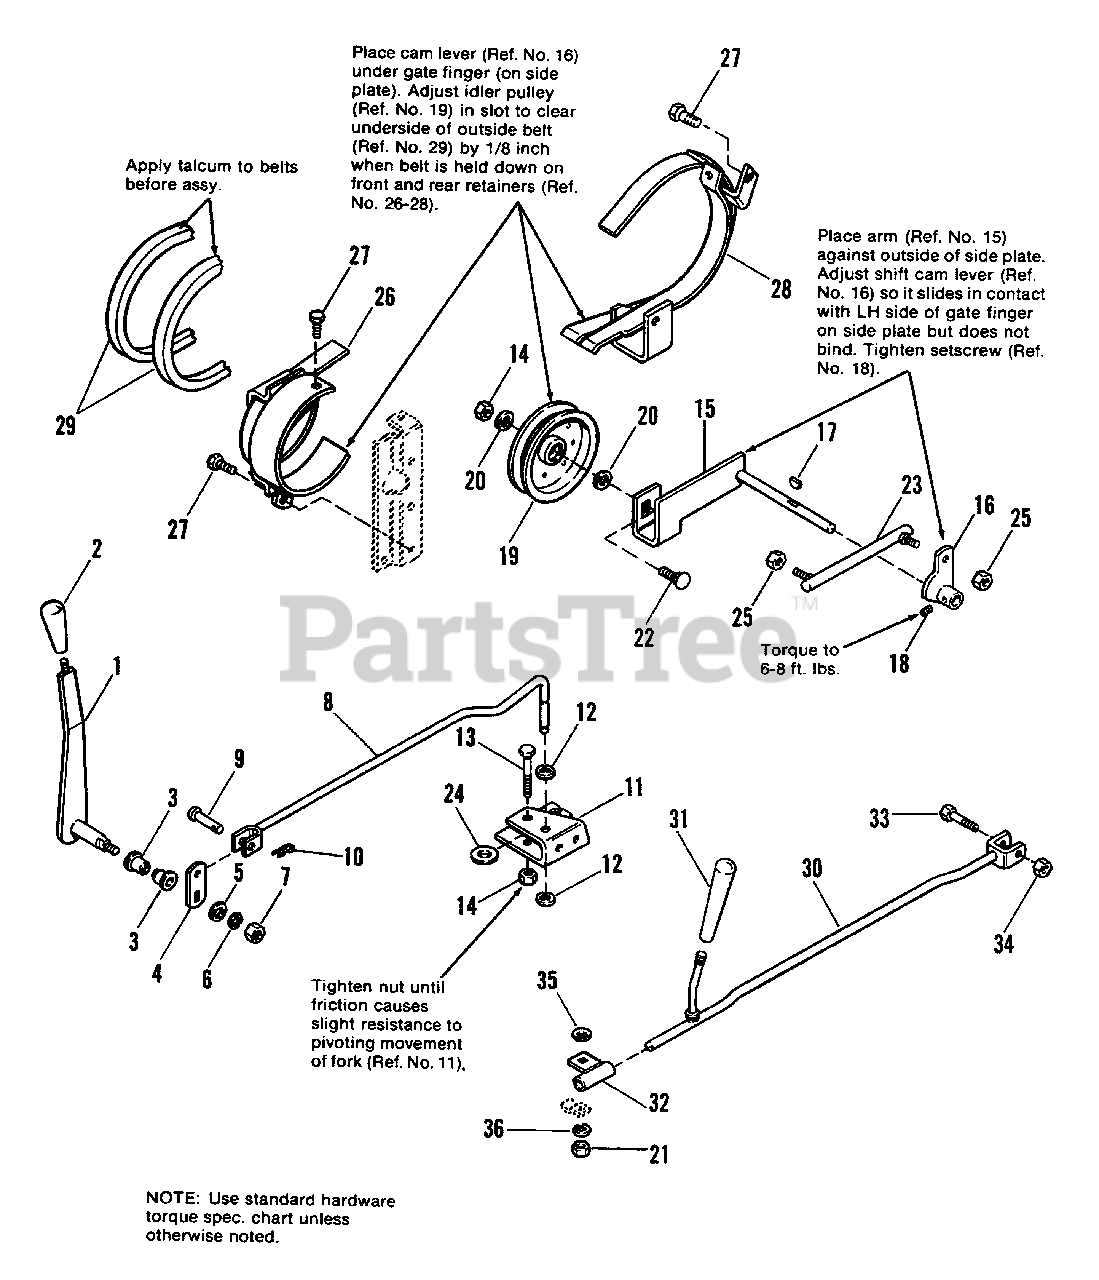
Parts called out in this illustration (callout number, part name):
1	CONTROL LEVER ASSY.
2	KNOB
3	BUSHING, Flanged
5	WASHER, 3/8
6	LOCKWASHER, 3/8
7	NUT, Hex, Full, 3/8-16
8	CONTROL ROD ASSY.
10	PIN, Cotter, 3/32 x 3/4
11	FORK, Shift
12	"E" RING, External
13	CAPSCREW, Hex Hd., 3/8-16 x 2
14	LOCKNUT, Hex, 3/8-16
15	IDLER ARM ASSY.
16	CAM SHIFT LEVER ASSY.
17	KEY, Woodruff, #5, 1/8 x 5/8
18	SETSCREW, Sq. Hd., 1/4-20 x 1/4
19	PULLEY, Idler
20	WASHER, 5/16
21	NUT, Hex, Full, 1/4-20
22	BOLT, Carriage, 3/8-16 x 1-1/4
23	JOINT, Ball, Dbl. End
25	LOCKNUT, Hex, Full, 5/16-24
26	BELT RETAINER ASSY.
27	SCREW, Taptite, 5/16-18 x 1/2
28	REAR RETAINER ASSY.
29	BELT,"V", Drive
30	SHIFT ROD ASSY.
31	HANDLE, Shift Rod
32	SHIFT ROD GUIDE ASSY.
33	CAPSCREW, Hex Hd., 5/16-18 x 1-1/2
34	NUT, Hex, Full, 5/16-18
35	WASHER, Cup
36	LOCKWASHER, 1/4
